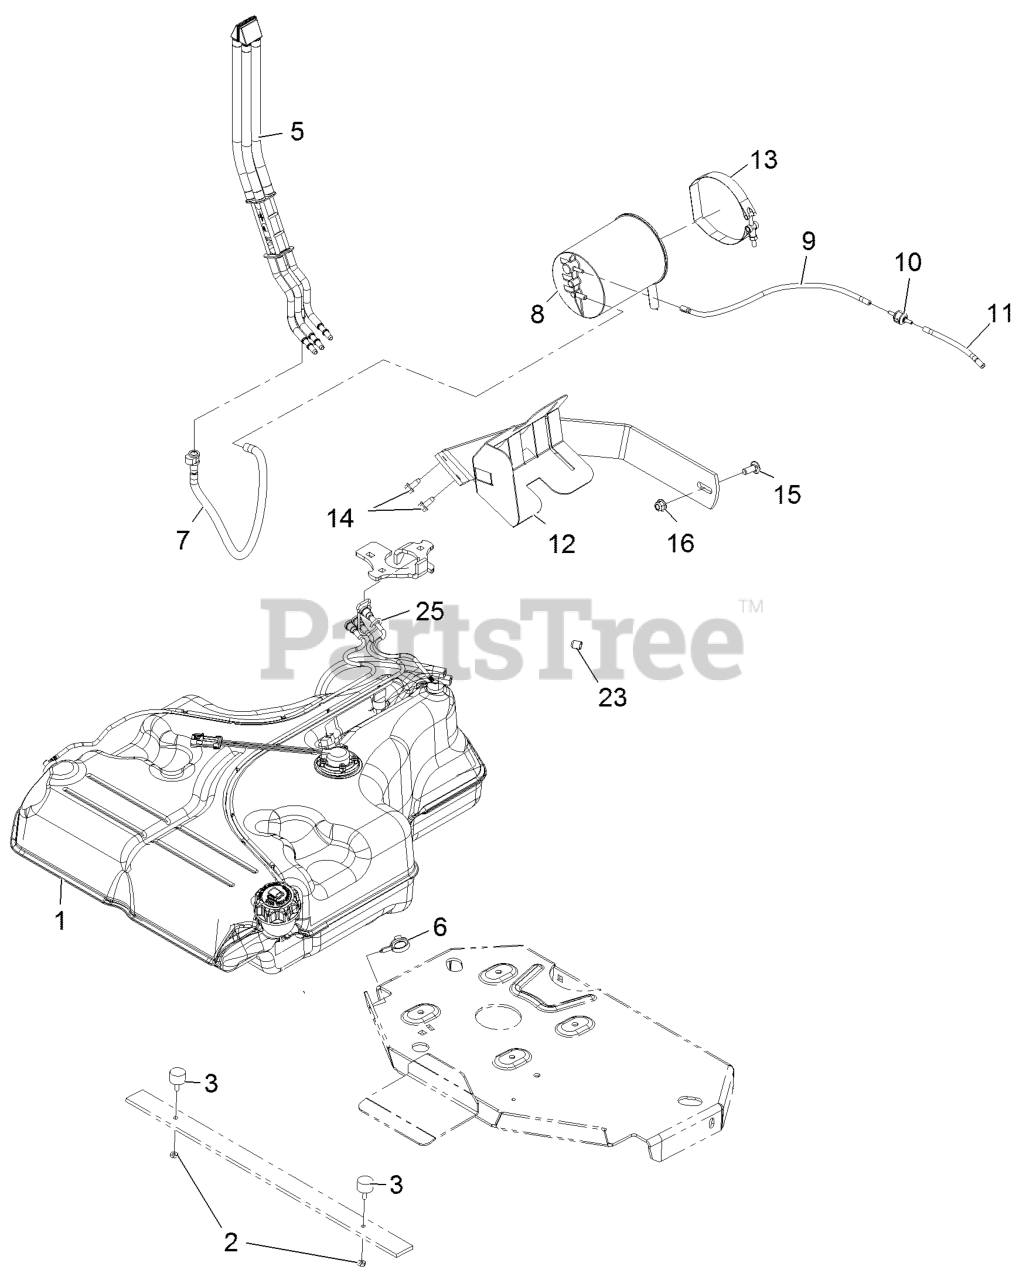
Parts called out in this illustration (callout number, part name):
2	NUT-JAM
5	FUEL MANIFOLD VENT ASM
6	CLAMP-HOSE
7	VENT HOSE ASM
8	CANISTER-CARBON, 1200CC
9	HOSE-VENT, FORMED
11	HOSE-VENT, FORMED
12	MOUNT-CANISTER
13	CLAMP, T-BOLT
14	Screw-HWH 5/16-18 X 3/4 Tf
15	SCREW-CARR
16	NUT-HF, NI
23	PLUG-PORT
25	RETAINER-LINE, VAPOR
